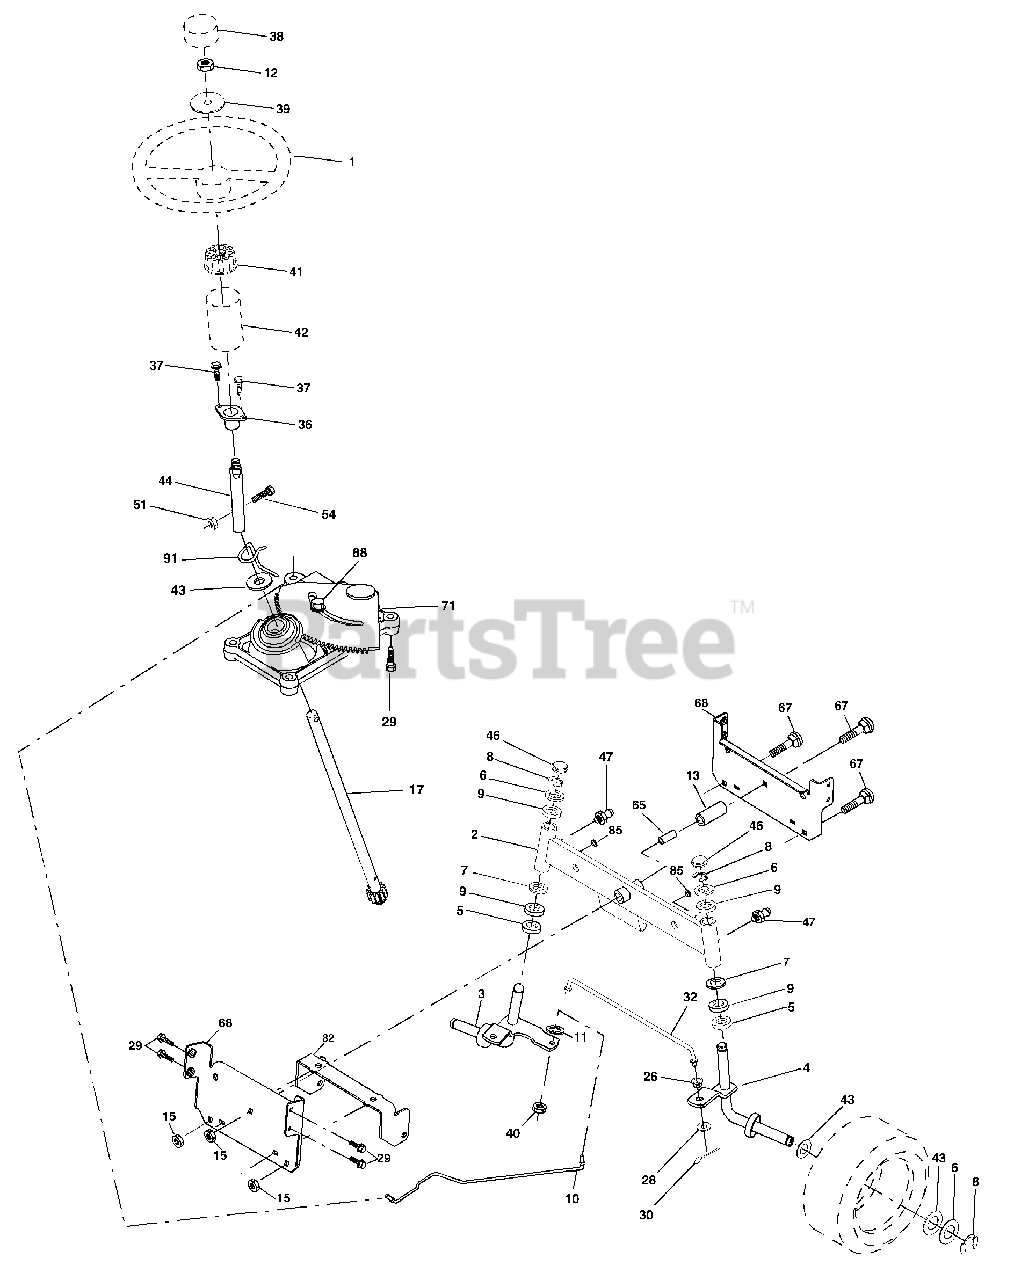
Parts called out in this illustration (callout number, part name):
1	Steering Wheel
2	Axle Assembly
3	Spindle Assembly, L.H.
4	Spindle Assembly, R.H.
5	Bearing, Race, Thrust, Hardened
6	Washer 25/32 x 1-5/8 x 16 Gauge
7	Washer 27/32 x 1-1/4 x 16 Gauge
8	Ring, Klip
9	Bearing, Steering Column
10	Draglink
11	Washer, Lock
12	Nut Hex Jam Toplock 1/2-20
13	Spacer Bearing Axle Front
15	Hexflange Lock
17	Shaft Assembly, Steering
26	Bushing, Link, Drag
28	Washer 13/32 x 7/8 x 16 Gauge
29	Screw, 3/8-16 x 3/4
30	Pin
32	Rod, Tie
36	Bushing, Steering
37	Screw
38	Cap, Steering Wheel
39	Washer 9/16 x 2-3/8
40	Gripco Nut
41	Adaptor, Steering Wheel
42	Boot, Steering
43	Washer 25/32 x 1-1/4 x 16 Gauge
44	Shaft Extension Steering
46	Cap, Spindle
47	Fitting, Grease
51	Nut 1/4-28
54	Bolt Hex 1/4-28 x 1-1/4
63	Bolt Fin Hex 3/8-16 x 1-1/4
65	Spacer Brace Axle
67	Bolt, Rdhd Sq 3/8-16 UNC x 2-1/4
68	Axle, Brace
71	Steering Asm
82	Bracket Susp Chassis Front
85	Fastener Christmas Tree
88	Shoulder Bolt
91	Clip Steering
